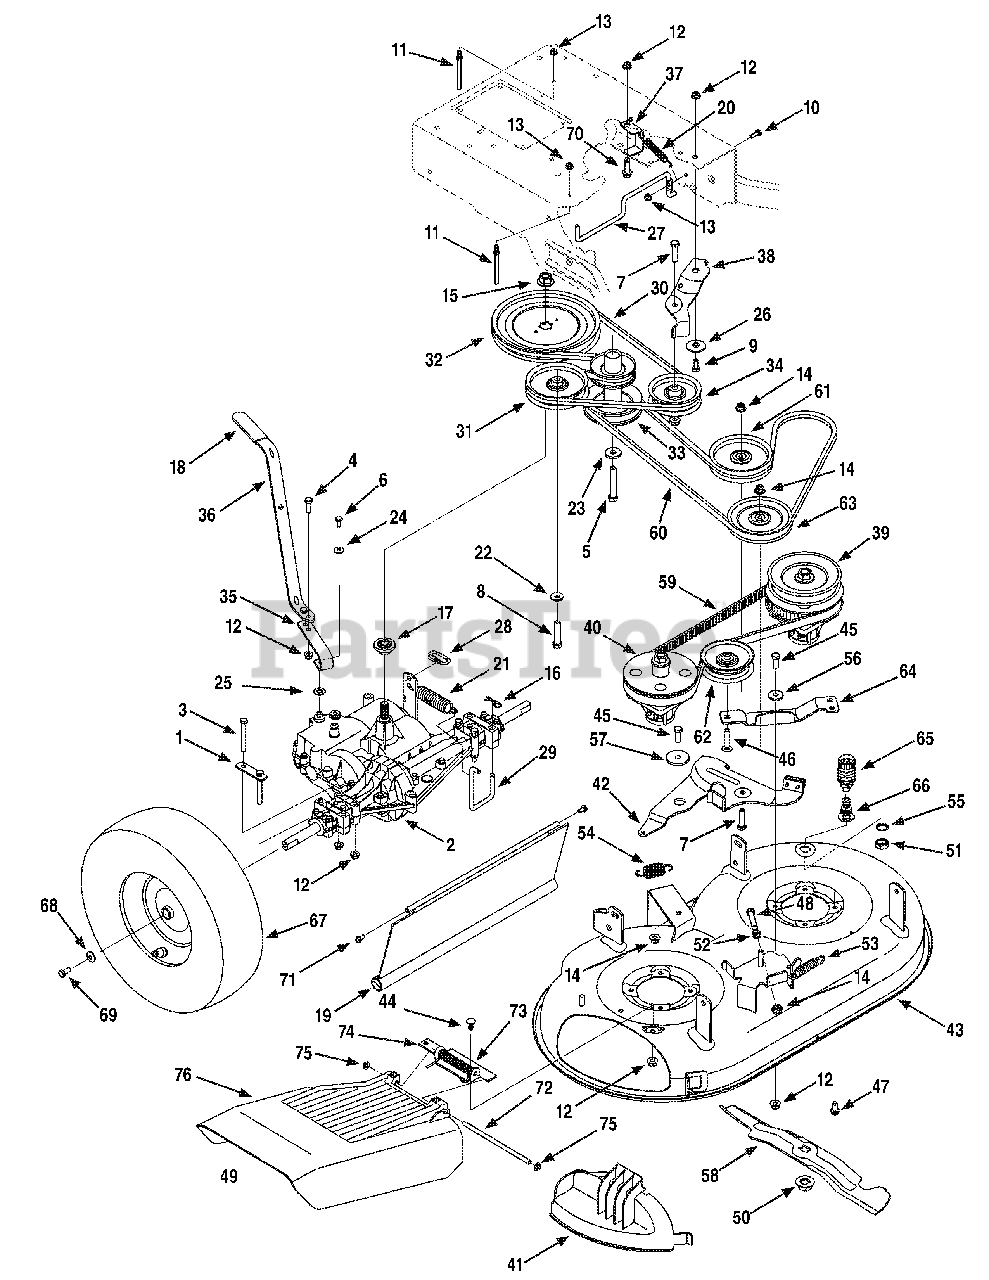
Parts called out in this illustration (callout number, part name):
1	Transaxle Bracket Mount
2	Transmission 4-Speed
3	Screw, HH Cap: 5/16-18 x 2.75"
4	Screw, HH Cap: 5/16-18 x 1.00"
5	Screw, HH Cap: 7/16-20 x 2.75"
6	Screw, HH Cap: 1/4-28 x .625"
7	Screw, HH Cap: 3/8-16 x 1.50"
8	Screw, HH Cap: 3/8-16 x 1.75"
9	Screw, HH Cap: 5/16-18 x .75"
10	Screw, HH Cap: 1/4-20 x .75"
11	Belt Keeper
12	Nut, Flange Lock: 5/16-18
13	Nut, Flange Lock: 1/4-20
14	Nut, Flange Lock: 3/8-16
15	Nut, Flange: 9/16-18
16	Hairpin Clip: 092" x 1.64" Long
17	Pulley Hub
19	Trailing Shield
20	Extension Spring
21	Extension Spring
22	Washer, Spring: .401" x .870" x .063"
23	Washer, Flat: 450" x 1.250" x .164"
24	Washer, Bell
25	Washer, Flat: .39" x .87" x .06"
26	Spacer, Shoulder: .50" x .1475"
27	Belt Keeper Rod
28	Loop Link Coupling
29	Trans Mount Rod
30	Belt, V Type
31	Idler Pulley: 4.25" Dia.
32	Flat Sheave 7.75"
33	Engine Pulley 3.20" x 4.35" Dia.
34	Idler Pulley 3.50" Dia.
35	Shift Rod, Lower
36	Shift Rod, Upper
37	Belt Keeper
39	Drive Spindle Assembly
40	Spacer Spindle Assembly
41	Mulch Plug
42	Idler Arm Assembly
43	Deck Assembly 33-inch
44	Bolt, Carriage: 5/16-18 x .75"
45	Screw, HH Cap: 3/8-16 x 1.00"
46	Screw, Carriage: 3/8-16 x 1.75"
47	Screw, LD: 5/16-18 x .750"
48	Screw, HH Cap: 3/8-16 x 2.00"
49	Chute Deflector Assy (includes ref. 72-76)
50	Nut, Flange: 5/8-18
51	Nut, Hex
52	Nut, Hex 3/8-16
53	Extension Spring: Timing Belt Tension
54	Extension Spring: Deck Brake
55	Washer, Lock
56	Spacer, Shoulder: .625" x .169"
57	Spacer, Shoulder: .884" x .190"
58	Blade: 17.9"
59	Belt, Timing
60	Belt, V Type
61	Idler Pulley 4.25"
62	Idler Pulley 3.50"
63	Idler Pulley V-Type 5.0"
64	Idler Timing Bracket
65	Water Nozzle Adapter
66	Water Nozzle
67	Wheel 16 x 4 x 8
68	Washer, Bell: .340" x .872" x .060"
69	Screw, HH Cap: 5/16-24 x .75"
70	Screw, TT: 3/8-16 x 1.25"
71	Screw, HL: 1/4-15 x .50"
72	Deflector Pin
73	Deflector Hinge Bracket
74	Deflector Torsion Spring
75	Push Cap
76	Chute Deflector, 33" SD Deck
